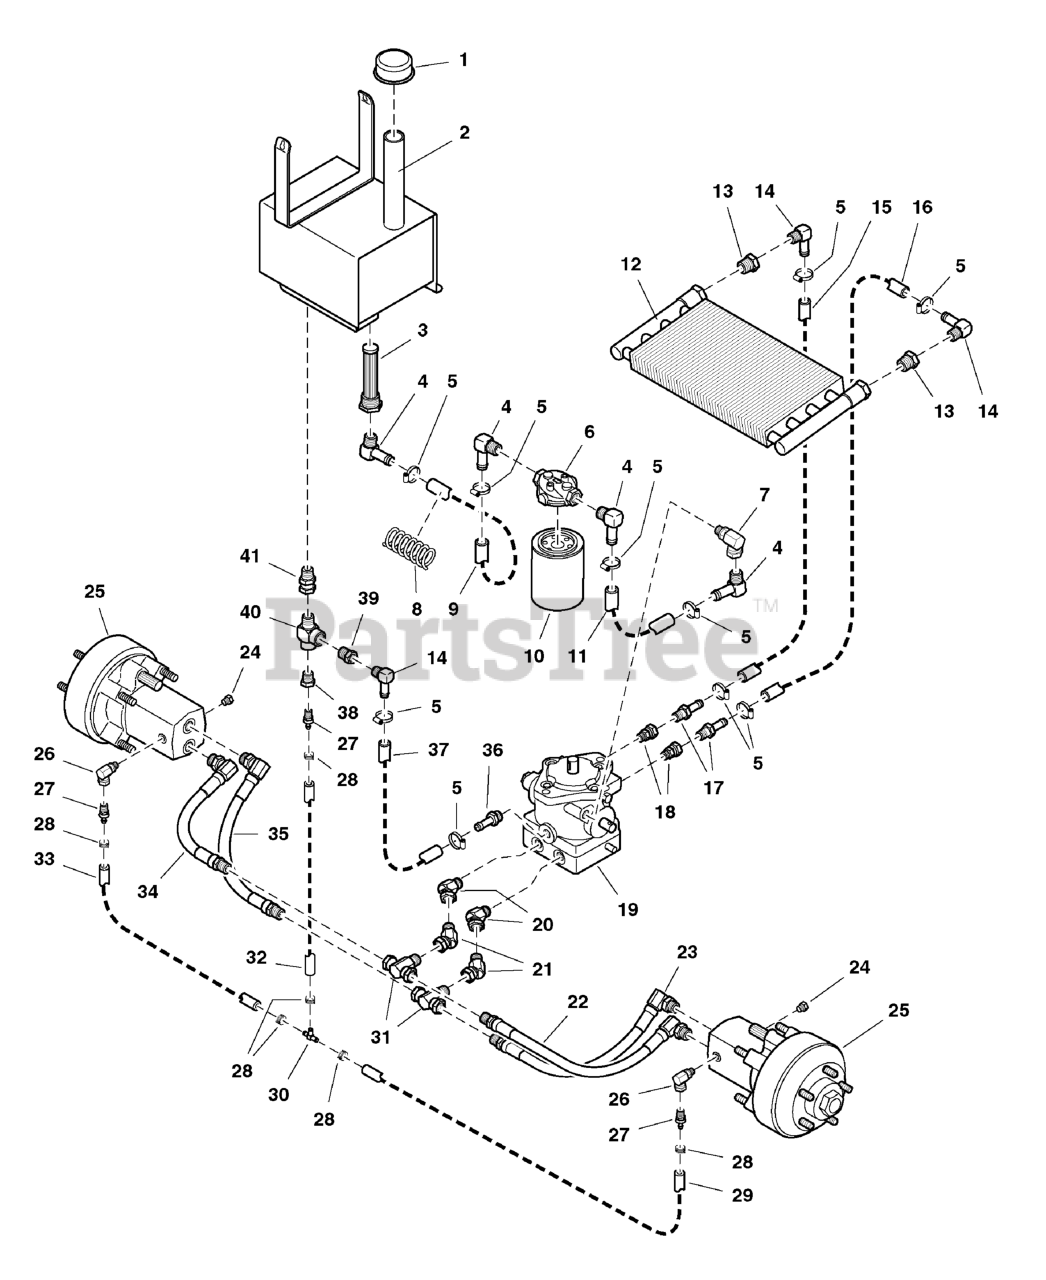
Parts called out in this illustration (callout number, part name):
1	BREATHER
2	HYDRO TANK ASSEMBLY, Complete
2	HYDRO TANK WELDMENT
2	FOIL TAPE
3	STRAINER
4	FITTING, 1/2" NPT, 90 Deg.
5	CLAMP, #6 Hose
6	FILTER HEAD
7	FITTING, O-Ring, 90 Deg.
8	SPRING, Compression
9	HOSE, Hydraulic, 22-3/4"
10	FILTER, HYDRAULIC, SERVICE PART (PKG)
11	HOSE, 9-3/4"
12	OIL COOLER
13	FITTING, Reducer
14	FITTING, NPT - Hose, 90 Deg.
15	HOSE, 29"
16	HOSE, 29"
17	FITTING, 3/8NPT-1/2" Hose, Straight
18	FITTING, O-Ring - NPT, Swivel
19	HYDRAULIC PUMP
20	FITTING, O-Ring - NPT, 45 Deg.
21	FITTING, 1/2 NPT, 45 Deg. Swivel
22	HOSE ASSEMBLY, 19"
23	HOSE ASSEMBLY, 17"
24	PLUG, O-Ring
25	HYDRAULIC WHEEL MOTOR
26	FITTING, 7/16" O-Ring 90 Degree Swivel
27	FITTING, Male Adapter
28	CLAMP, Hose
29	HOSE, 25"
30	FITTING, Tee
31	FITTING, Tee
32	HOSE, 2-1/4"
33	HOSE, 6-1/4"
34	HOSE ASSEMBLY, 13"
35	HOSE ASSEMBLY, 15"
36	FITTING, O-Ring - Hose
37	HOSE, 10-1/2"
38	FITTING, Reducer
39	FITTING, Reducer
40	FITTING, Tee
41	FITTING, Straight Swivel
